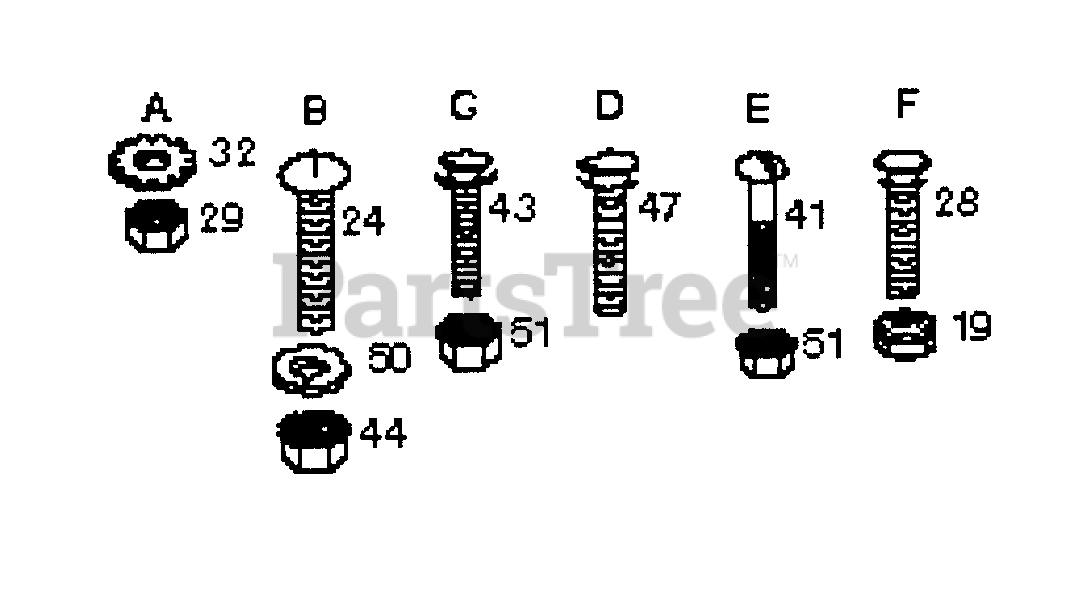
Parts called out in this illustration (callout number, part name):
19	Nut, Hex 1/4 - 20
24	Screw 10/32 x 1/2 Pan Head UNF
28	Bolt, Hex 1/4 - 20 x 1/2 Gr. 5
29	Nut, Keps, Hex 1/4- 20
32	Washer, Lock 1/4 - 20 Ext. Tooth
41	Slotted Pan Head Screw #10-32
43	Hex Washer Head Screw
44	Nut, Keps #10-32 UNF
47	Screw, Hex Tapping #10-24 x 1/2
50	Washer, Lock 1/4
